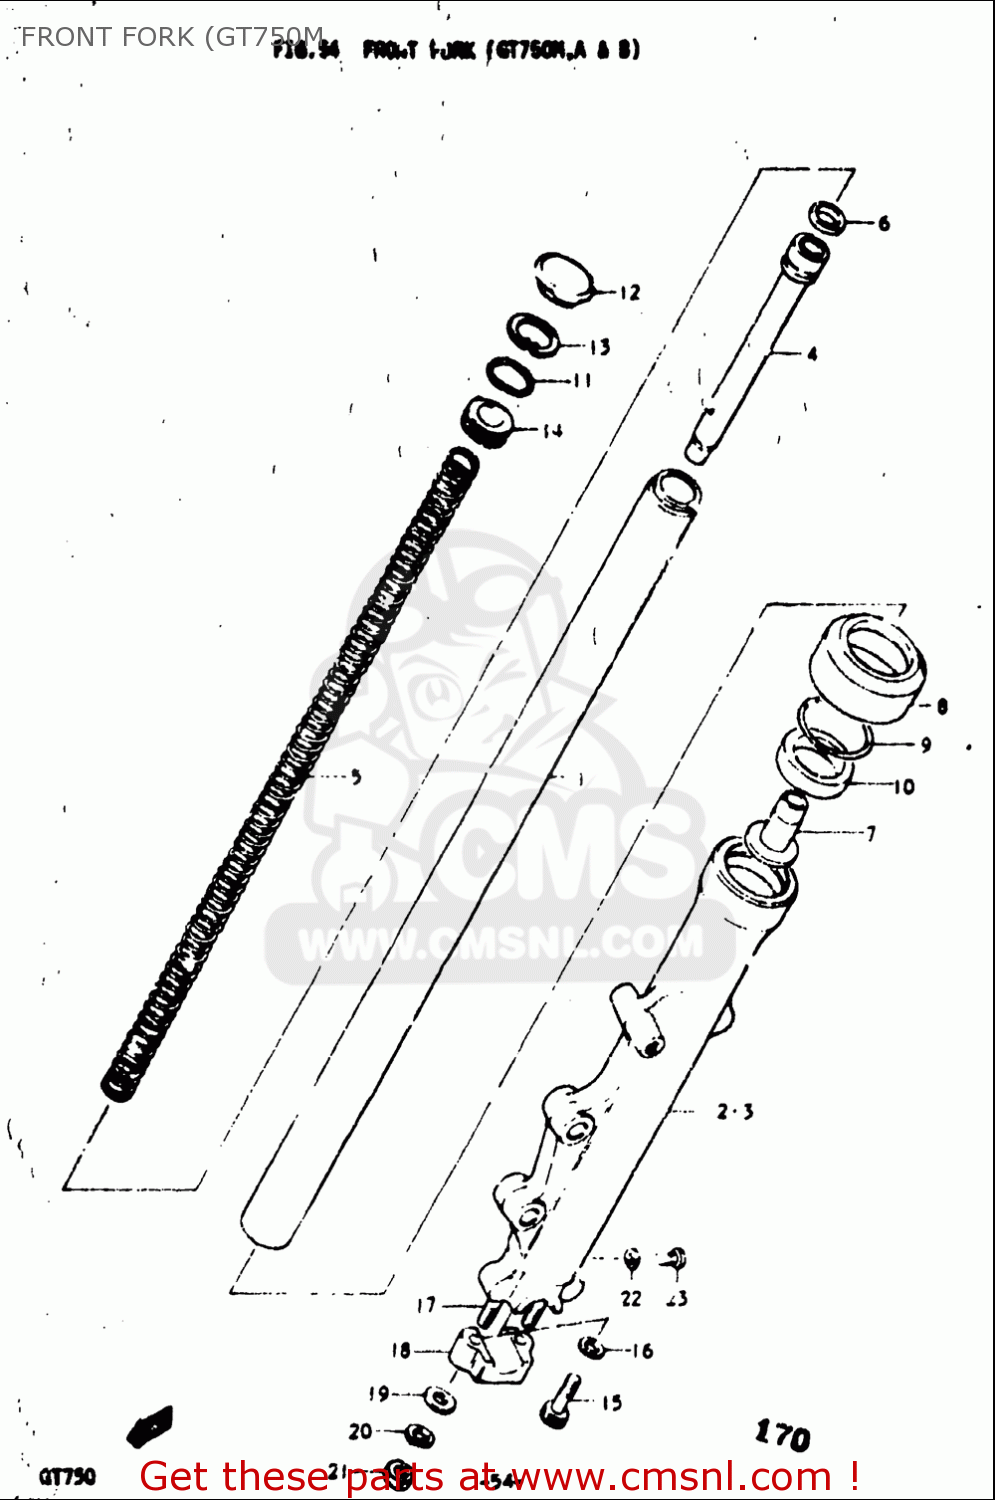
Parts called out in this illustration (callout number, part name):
6	RING
7	PIECE,OIL LOCK
8	DUST SEAL,FR FORK
9	RING,OIL SEAL STOPPER
10	SEAL,OIL 35X48X11
11	O RING
12	CAP
13	CIRCLIP
15	BOLT(8X27)
16	GASKET (NAS)
17	STUD 8X25
18	HOLDER,AXLE
19	WASHER
20	WASHER,LOCK
21	NUT
22	GASKET (NAS)
23	SCREW 4X6
